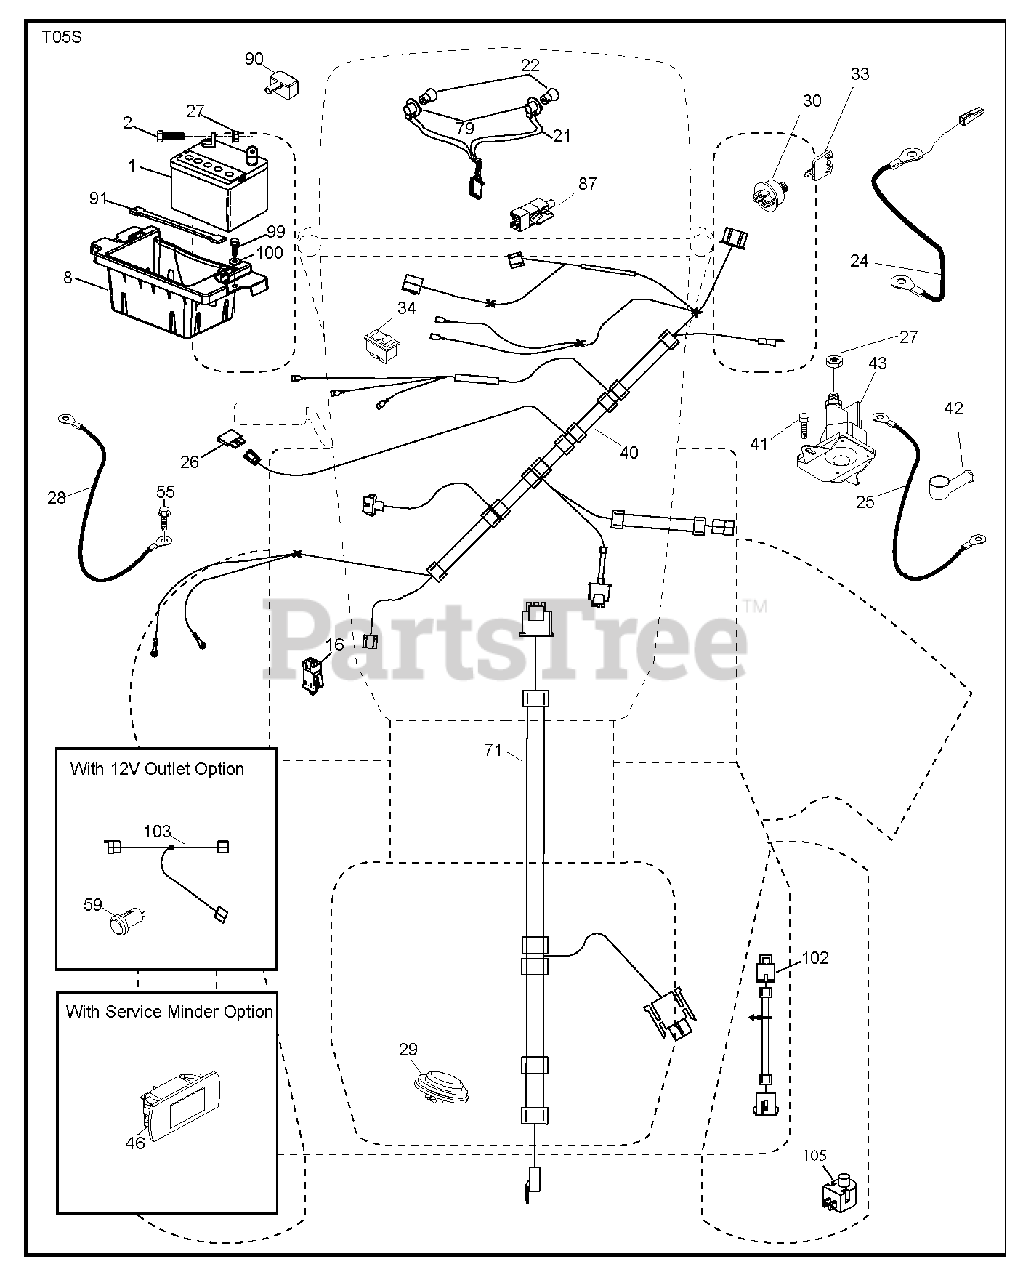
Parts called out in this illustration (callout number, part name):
1	Battery, Dry 30 Amp
2	BOLT.HEX.1/4.X.3/4.DICHROMATE
8	BOX.BATTERY.MOUNT.FRONT.LT
16	SWITCH INTERLOOK PUSH-IN
21	HARNESS.LIGHT W/4152J BULBS
24	CABLE.BATT.POS.WIRE.TG.DA SOL
25	CABLE.STARTER.6G.BL/RED.17.5
26	FUSE 20AMP
27	NUT
28	CABLE GROUND 6 GA 21" 90T BLK
29	SWITCH.SEAT.DELTA.OPC.
30	SWITCH.IGN.DELTA.W.LGH.ROS
33	KEY.CHAIN.BLISTER.PACK.GEN.INT
40	HARNESS IGN. DASH
41	SCREW
42	TERMINAL COVER
43	SOLENOID.W/BRASS.PLUNGER
46	RP GUAGE.SRVCMNDR.HRMTR.
55	SCREW 5/16"
71	HARNESS-CHASSIS SUB
79	BULB HOLDER ASM.
87	SWITCH.INTRLCK.CLUTCH.
90	COVER.TERMINAL.BATTERY
91	STRAP.BATTERY.MOUNT.FRONT(2 2)
99	SCREW HEXWSHR 1/4-20X3/4
102	HARNESS PIGTAIL PCH TEX ROS
105	REVERSE SWITCH
